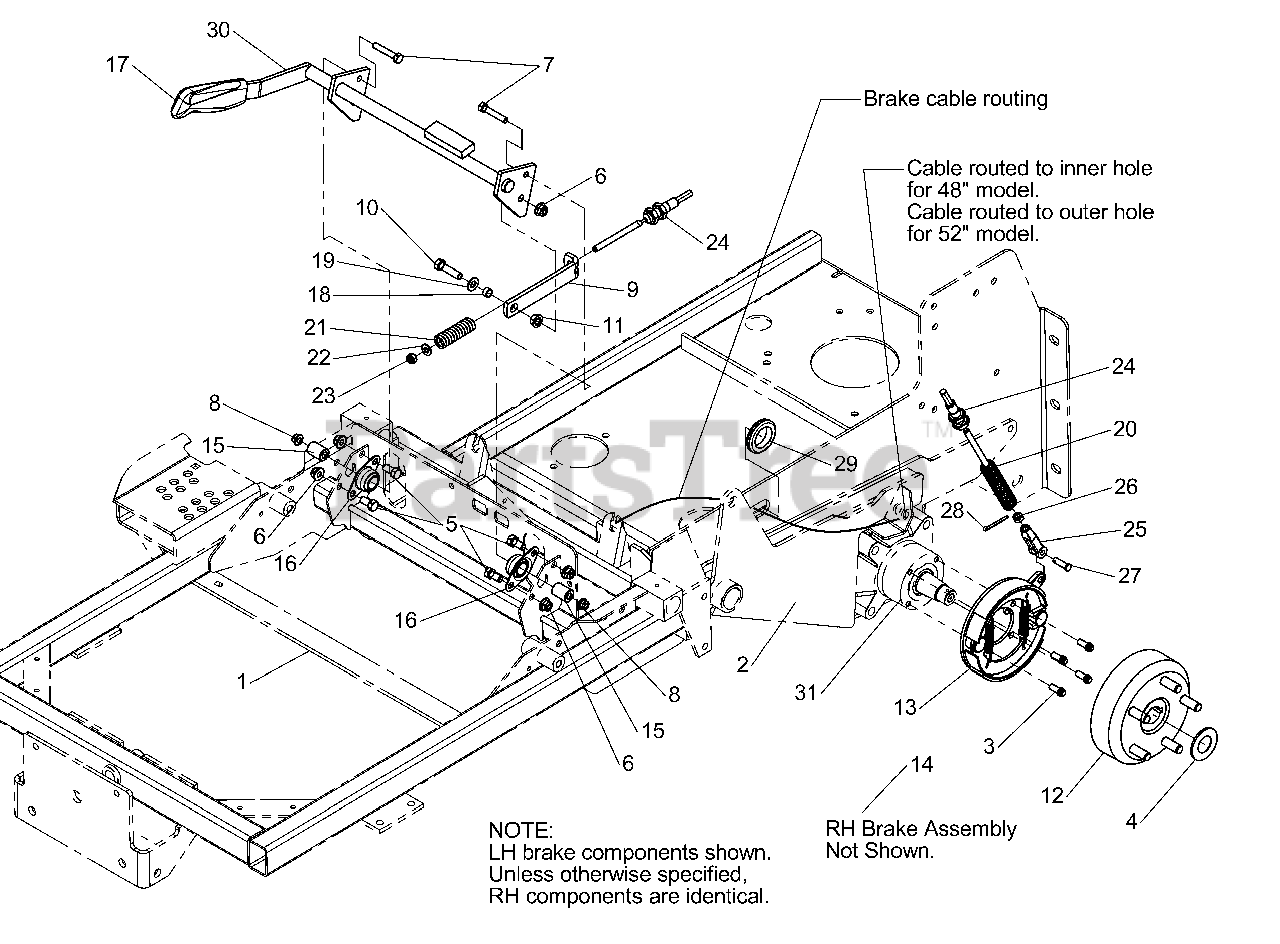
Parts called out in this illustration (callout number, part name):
1	MAIN FRAME (See Main Frame Group)
2	MOTOR MOUNT (See Rear Suspension Group)
3	BOLT, 5/16-18 X 3/4" 12 Point Flange
4	WASHER, 1 x 2
5	BOLT, 3/8-16 X 3/4"
6	NUT, 3/8-16 Hex Nylock Flange
7	BOLT, 5/16-18 X 1-3/4"
8	NUT, 5/16-18 Hex Nylock Flange
9	LINK, BRAKE STOP, 6.0 - BLK
10	BOLT, 3/8-16 X 1-1/2"
11	NUT, 3/8-16 Hex Serrated Flange
12	BRAKE DRUM, 6", 5 BOLT, KNOTT
13	BRAKE ASSEMBLY, LH
15	SPACER, .32 X .75 X 1.06
16	BEARING, Flange
18	SPACER, .38 X .50 X .27
19	WASHER, 3/8" SAE
20	SPRING, Compression
21	SPRING, Compression
22	WASHER, 5/16" SAE
23	NUT, 5/16-24 Hex Nylon Lock
24	PARKING BRAKE CABLE
25	CLEVIS, 5/16-24, Plastic
26	NUT, 5/16-24 Hex
27	CLEVIS PIN, 5/16" X 1"
28	COTTER PIN, 1/8" X 1-1/4"
29	GROMMET, 1-1/4"
30	BRAKE SHAFT
31	WHEEL MOTOR (See Hydraulic Group)
